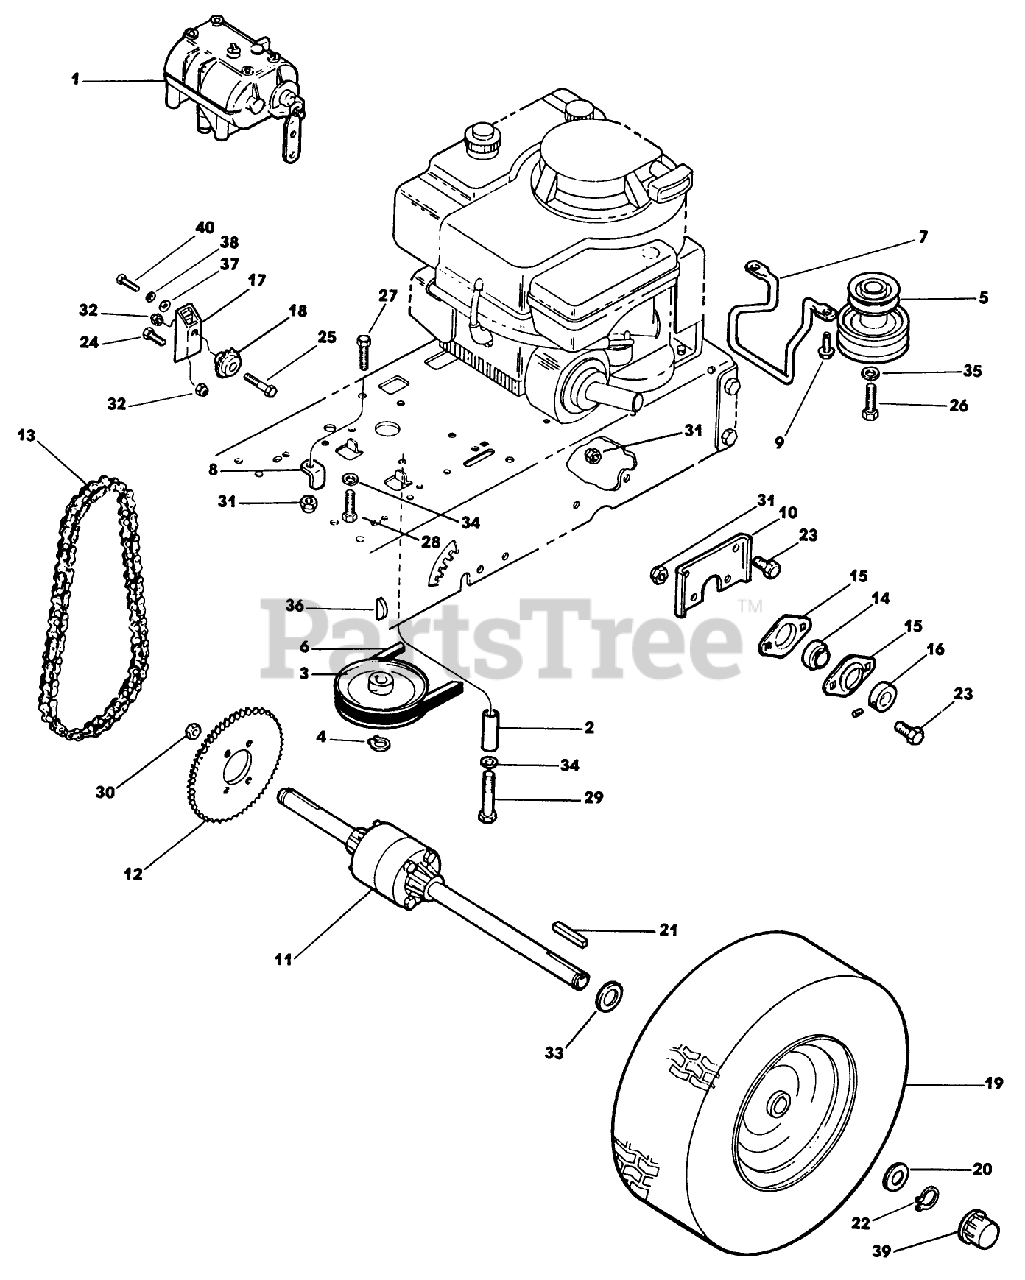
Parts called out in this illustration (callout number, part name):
2	GUIDE - BELT
6	V-BELT S
9	SCREW-THREAD FRMG
12	SPROCKET - RH
14	DISCONTINIUED
15	FLANGETTE-BEARING
16	COLLAR-BEARING
17	IDLER SPRKT BRKT WA*B
20	WASHER
22	RING-RETAINING
23	SCREW - HEX
27	SCREW
31	NUT
32	NUT-LOCKING
38	WASHER
